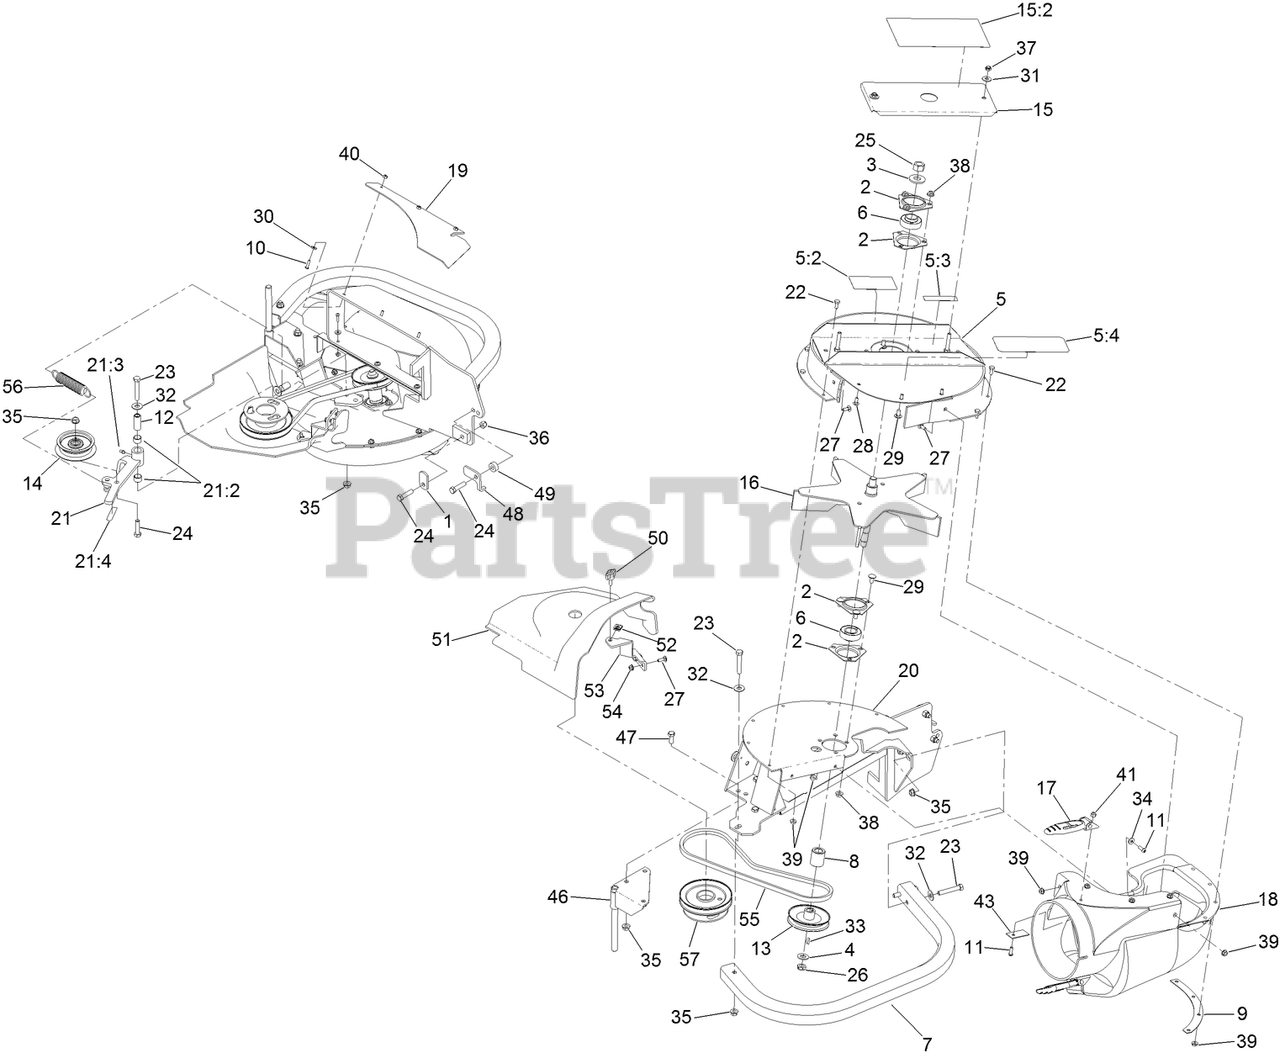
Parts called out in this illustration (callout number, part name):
1	LATCH-CATCHER, GRASS
2	HOUSING-FLANGE
3	WASHER-SPRING
4	WASHER-FLAT
5	UPPER HOUSING ASM
5:2	DECAL-WARNING
5:3	DECAL-COVER, MISSING
6	BEARING
8	SPACER
9	PLATE-BACKING, BLOWER
10	SCREW-HSBH
11	SCREW-HSBH
12	BUSHING
13	SHEAVE
14	IDLER-FLAT
15	COVER-BEARING
15:2	Decal, Warning
16	IMPELLER
17	LATCH-RUBBER
18	CHUTE-BLOWER
19	PLATE-BOTTOM
20	MOUNT-BLOWER
21	IDLER ARM ASM
21:2	BUSHING
21:3	FITTING-GREASE
21:4	DECAL-WARNING
22	SCREW-HH
23	SCREW-HH
24	SCREW-HH
25	NUT-HEX
26	NUT-LOCK, NI
27	BOLT-CARR
28	SCREW-CARR
29	SCREW-CARR
30	WASHER-FLAT
31	WASHER-FLAT
32	WASHER-FLAT
33	KEY-WOODRUFF
34	WASHER-FLAT
35	NUT-HHF, WHIZ
36	NUT-LOCK, NI
37	NUT-LOCK, NI
38	NUT-HF
39	NUT-HF
40	NUT-LOCK, NI
41	NUT-LOCK, NI
43	PLATE-BACKING
46	PIN-MOUNT
47	SCREW-HH
48	LATCH-STOP
49	SPACER
51	SHIELD-BELT, 60IN
52	NUT-SPEED
53	BRACKET-COVER, BELT (60/72)
54	NUT-HF
55	BELT-V
56	SPRING-EXTENSION
